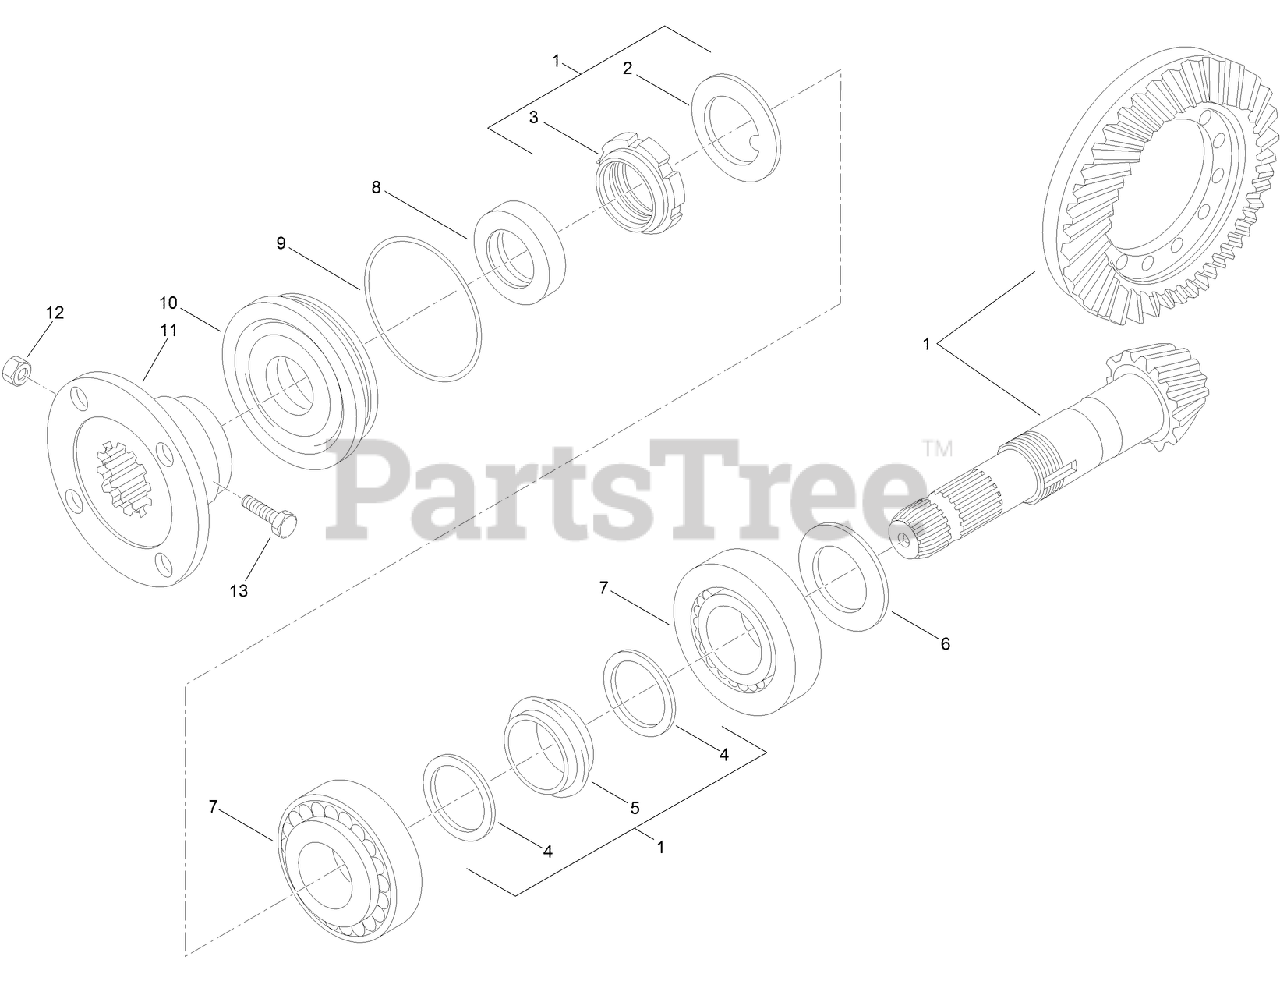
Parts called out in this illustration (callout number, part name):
1	BEVEL GEAR SET
2	LOCKWASHER
3	NUT-RING
4	WASHER
5	SPACER-COLLAPSIBLE
6	SHIM (3.40MM)
6	SHIM (3.30MM)
6	SHIM (3.20MM)
6	SHIM (3.10MM)
6	SHIM (3.00MM)
6	SHIM (2.90MM)
6	SHIM (2.80MM)
6	SHIM (2.60MM)
6	SHIM (2.50MM)
6	SHIM (2.70MM)
7	BEARING
8	RING-SEAL, OIL
9	O-RING
10	COVER-SEAL, OIL
11	FLANGE
